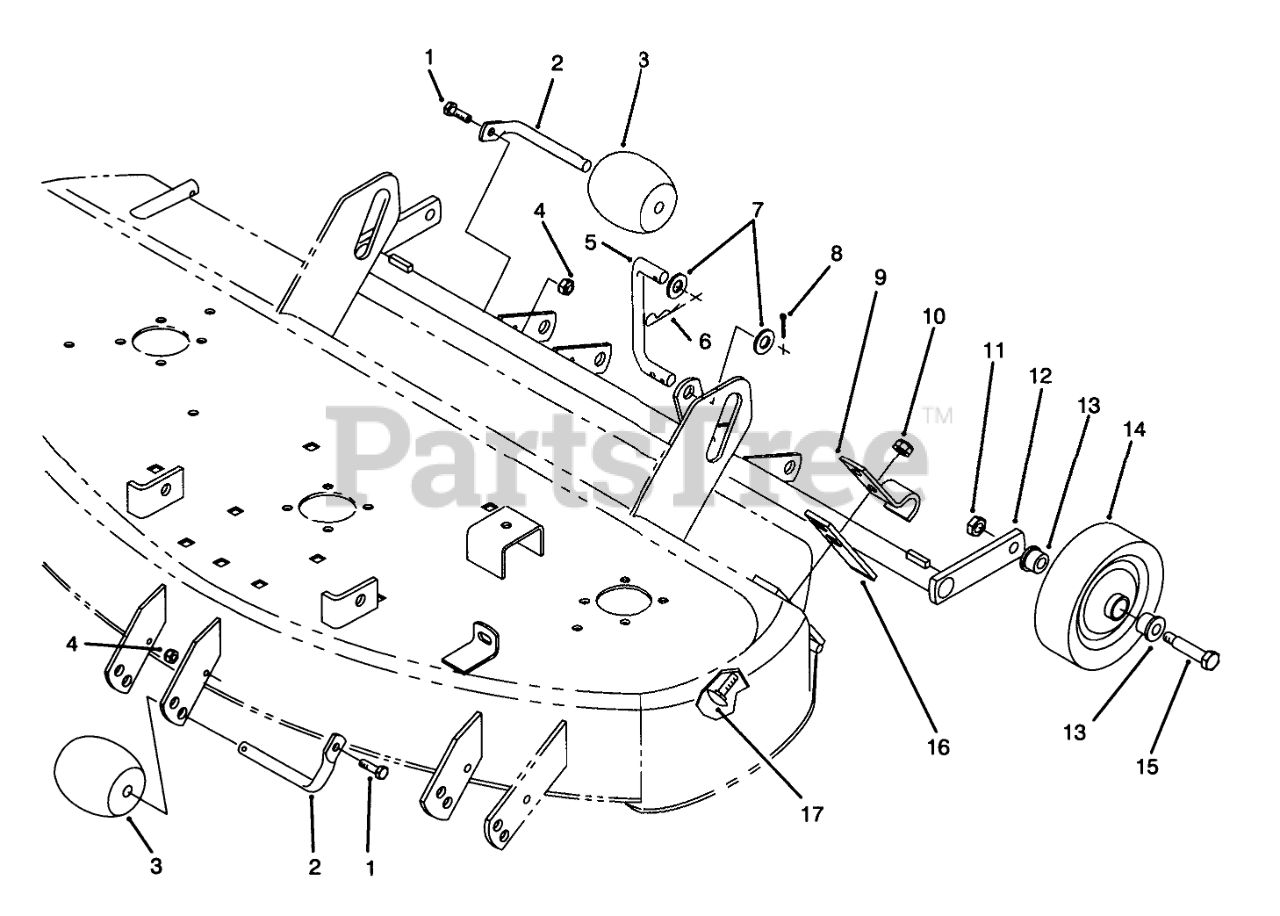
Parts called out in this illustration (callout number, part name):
1	Bolt
2	SHAFT-ROLLER
3	ROLLER
4	NUT-LOCK, NI
5	LINK-REAR
6	Pin-Cotter
7	WASHER-FLAT
8	PIN-COTTER
9	Clamp
10	NUT-LOCK, NI
11	NUT-HEX
12	Gage Wheel Support W.A.
13	BEARING
14	Assembly-Wheel (Incl. Ref. #13)
15	BOLT-SHOULDER
16	Bar
17	SCREW-CARR
